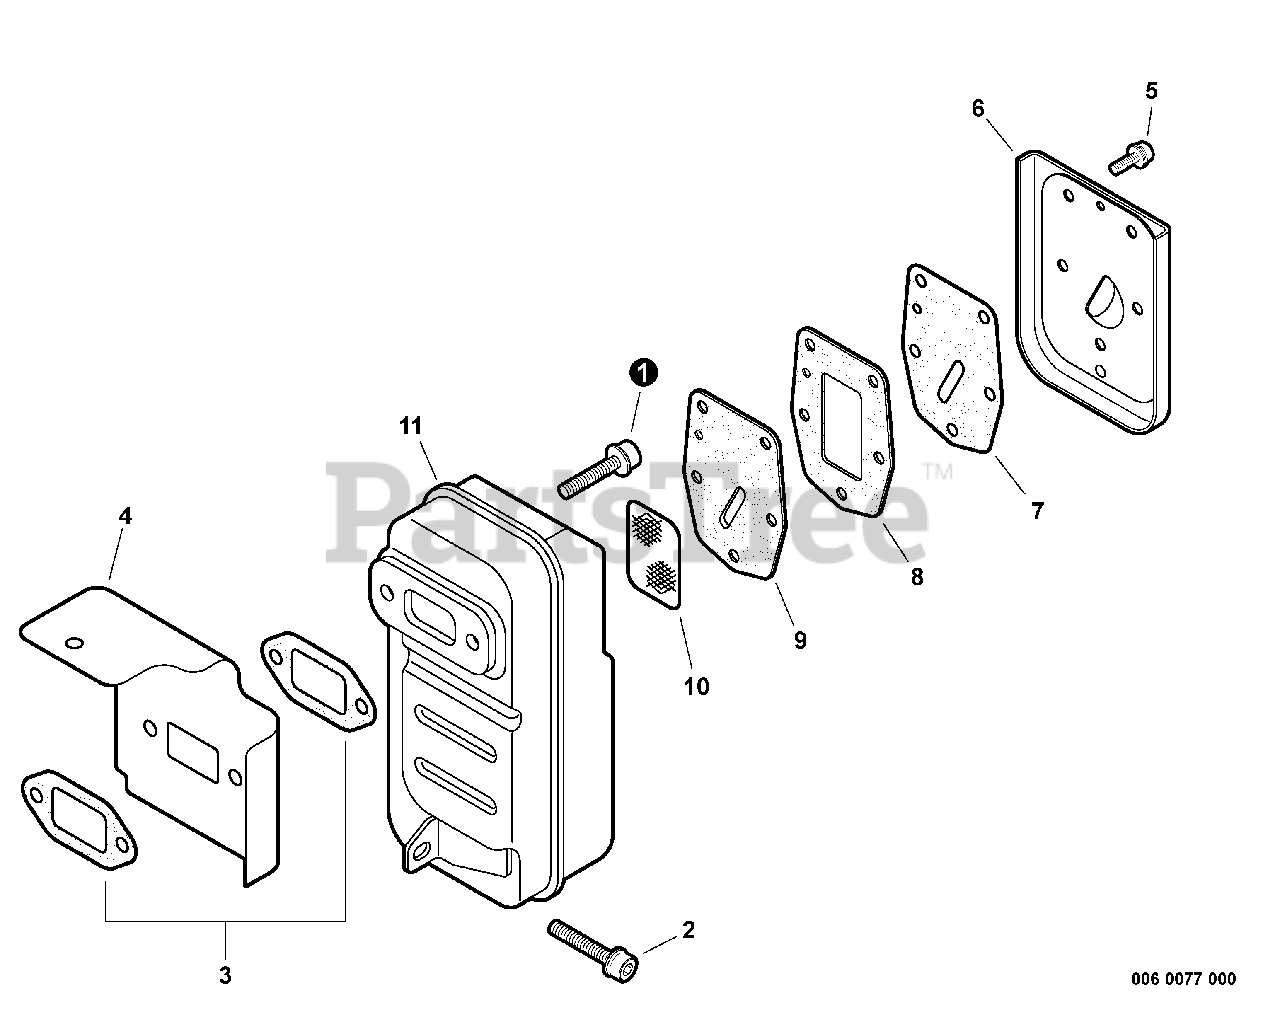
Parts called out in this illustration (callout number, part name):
1	BOLT 6×20
2	BOLT 5×20
3	GASKET, EXHAUST
4	COVER, ENGINE - EXHAUST
5	SCREW 4×14
6	GUIDE, EXHAUST
7	GASKET, EXHAUST
8	GASKET, EXHAUST
9	GASKET, EXHAUST
10	SCREEN, SPARK ARRESTER
11	MUFFLER
